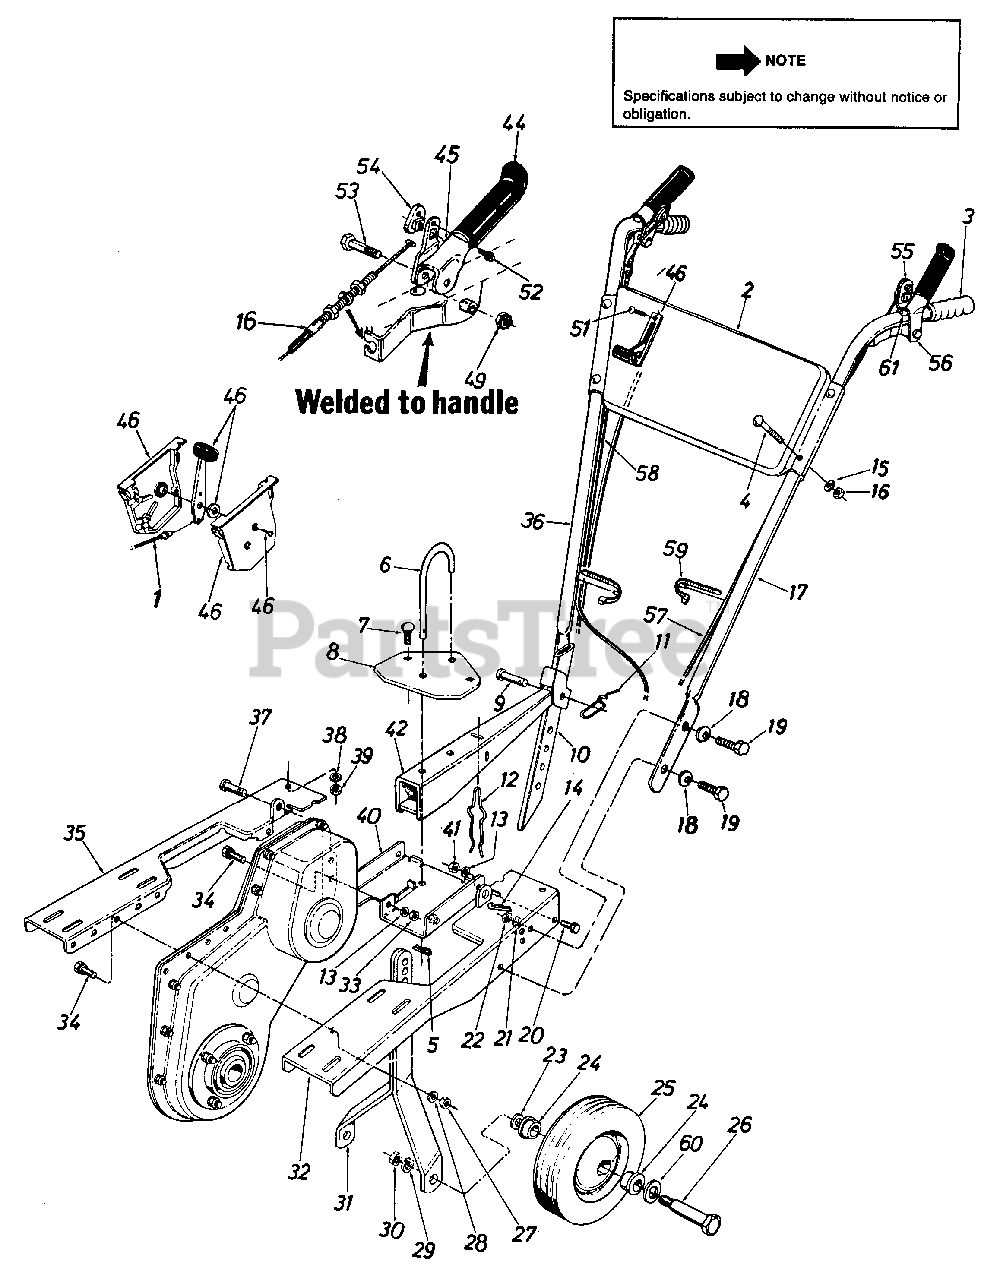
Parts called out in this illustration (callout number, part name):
1	WIRE-CONTROL
2	PANEL-HANDLE
3	GRIP-BLACK
4	BOLT-CARRIAGE 5/16-18 X 1.75
5	PIN-COTTER
6	PIN-CLEVIS .50 DIA
7	BOLT-CARRIAGE 5/16-18 X .75
8	PLATE-U CHANNEL
9	PIN-CLEVIS
10	BAR-DEPTH
11	PIN-SPRING
12	SPRING-DEPTH BAR
13	WASHER-LOCK-5/16
14	PIN-COTTER
15	WASHER-LOCK-5/16
16	NUT-HEX 5/16-18
19	SCREW-HEX 3/8-16 X 1.00
20	SCREW-HEX 5/16-18 X .75
21	WASHER-LOCK-3/8
22	NUT-HEX 3/8-16
23	WASHER-BELL .505 ID X 1.00 OD
24	BEARING-FLANGE
25	WHEEL ASSY-10 X 1.75
26	SCREW-SHLD
27	NUT-HEX 5/16-18
28	WASHER-LOCK-5/16
29	WASHER-LOCK-1/2
30	NUT-HEX INS L-1/2-20
31	BRACKET ASSY-WHL
32	CHANNEL ASSY-U-LH
33	NUT-HEX 5/16-18
34	SCREW-HEX SEMS 5/16-18 X 1.00
35	CHANNEL-ENG U
36	HANDLE ASSY-RH
37	PIN-CLEVIS
38	WASHER-LOCK-5/16
39	NUT-HEX 5/16-18
40	BRACKET ASSY-U CHANNEL
41	NUT-HEX 5/16-18
42	TAIL PIECE ASSY
45	GRIP ASSY-CLUTCH-RH
46	CONTROL BOX-THROTTLE
49	NUT-HEX INS L-3/8-24
51	SCREW-TRUSS TAP
52	SCREW-TAP
53	SCREW-HEX 3/8-24 X 2.00
54	HOLD DOWN-BARREL-RH
55	HOLD DOWN-CABLE
57	CABLE-CLUTCH CONTROL
58	CABLE-CLUTCH CONTROL
59	TIE-CABLE
60	WASHER-FL-.640ID X 1.24OD X .06HDN
61	BUMPER-RUBBER
